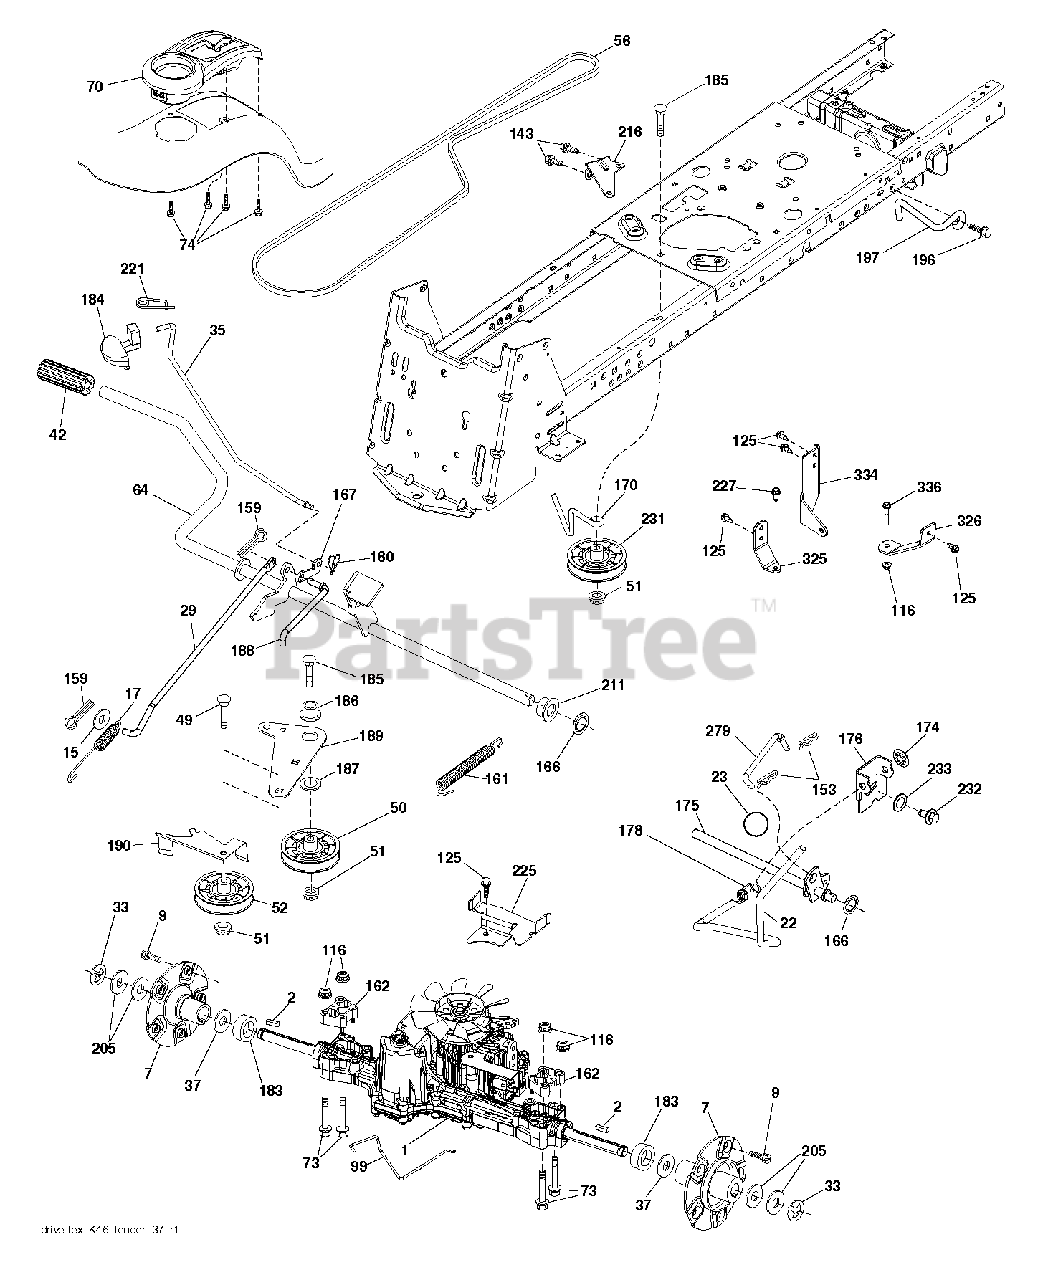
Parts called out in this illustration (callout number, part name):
2	KEY.SQUARE.187X2.500
7	HUB.ASM.WHEEL.REAR.22"
9	HUB BOLT
17	SPRING.BRAKE.K46.GREEN
22	ROD.SHIFT.FENDER.STGT.
23	KNOB.DELUXE.(PISTOL.GRIP).BLAC
29	ROD.BRAKE.K46
33	E-RING LT
35	ROD .BRAKE. PARKING. GT. HUSQ.
37	WASHER.HARDENED
49	BOLT
50	IDLER.FLAT.910.OFFSET
51	NUT LOCK FLG 3/8-16 UNC
52	IDLER.V-GROOVE.910.OFFSET
56	V-BELT.MOWER.92.40.42/K46
64	SHAFT.ASM.PEDAL.BRAKE.
70	PAD.FOOTREST.RH.STGT.BLACK
73	Hex Flange Bolt, 5/16-18 X 3.75
74	SCREW.HI-LO.CONSOLE
99	ROD.SPRING.BYPASS.K46.TEX.GT
116	NUT LOCK HEX FLANGE 5/16-18
125	SCREW
143	SCREW LT
159	COTTER PIN
160	RETAINER CLIP
161	SPRING, RETURN LT
162	SPACER.TRANSAXLE.1"
166	NUT.PUSH.625
167	LATCH.BRAKE.SPRING
170	KEEPER.CENTER SPAN.1.688
174	NUT.PUSH.500.2006
175	SHAFT ASM SHIFT
176	ARM.CLEVIS.ROD.SHIFT
178	SPRING.SHIFT.GT2006
183	SPACER.SPLIT.800X.350
186	SPACER.RETAINER
187	WASHER 12/32X2X10GA
188	LINK.CLUTCH.GROUND.DRIVE
189	BELLCRANK.GROUND.DRIVE.TEX.
190	KEEPER.BELLCRANK.DRIVE
196	SCREW 3/8-16X1
197	BRKT.ANIT-ROTATION.CLUTCH
211	BUSHING.SHAFT.BRAKE.HAND
216	BRACKET.PULLEY.IDLER.W/TEX
221	RETAINER.SPRING.CLIP.H
225	KEEPER.BELT.TRANSAXLE.K46
227	Screw, Lt
231	IDLER.V-GROOVE.1.688.OFFSET
232	BOLT FIN HEX 7/16-14 X 1
233	WASHER SERRATED
279	LINK.SHIFT.T/A.K46.FEND.TX
325	Torque Strap Bracket, 46 22" Tire LH
326	Torque Strap Bracket, 46 22" Tire RH
334	Sway Rod Bracket, K46 X431
336	Flanged Hex Bolt, 5/16-18 X 1-3/4
